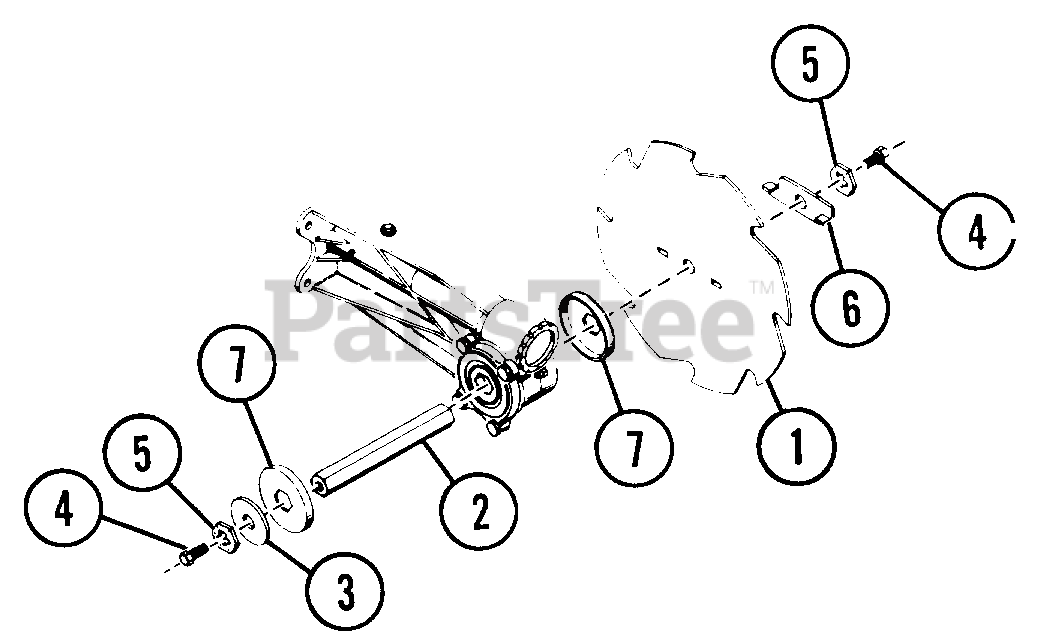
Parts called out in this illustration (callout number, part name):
1	LAWN EDGER
2	HEX SHAFT
3	WSHR-FL-STL .390X1.500X.125
4	BLT-HEX .38-24X.75 GR5
5	WSHR-LK .375X.130
6	TINE RETAINER
7	DUST COVER
